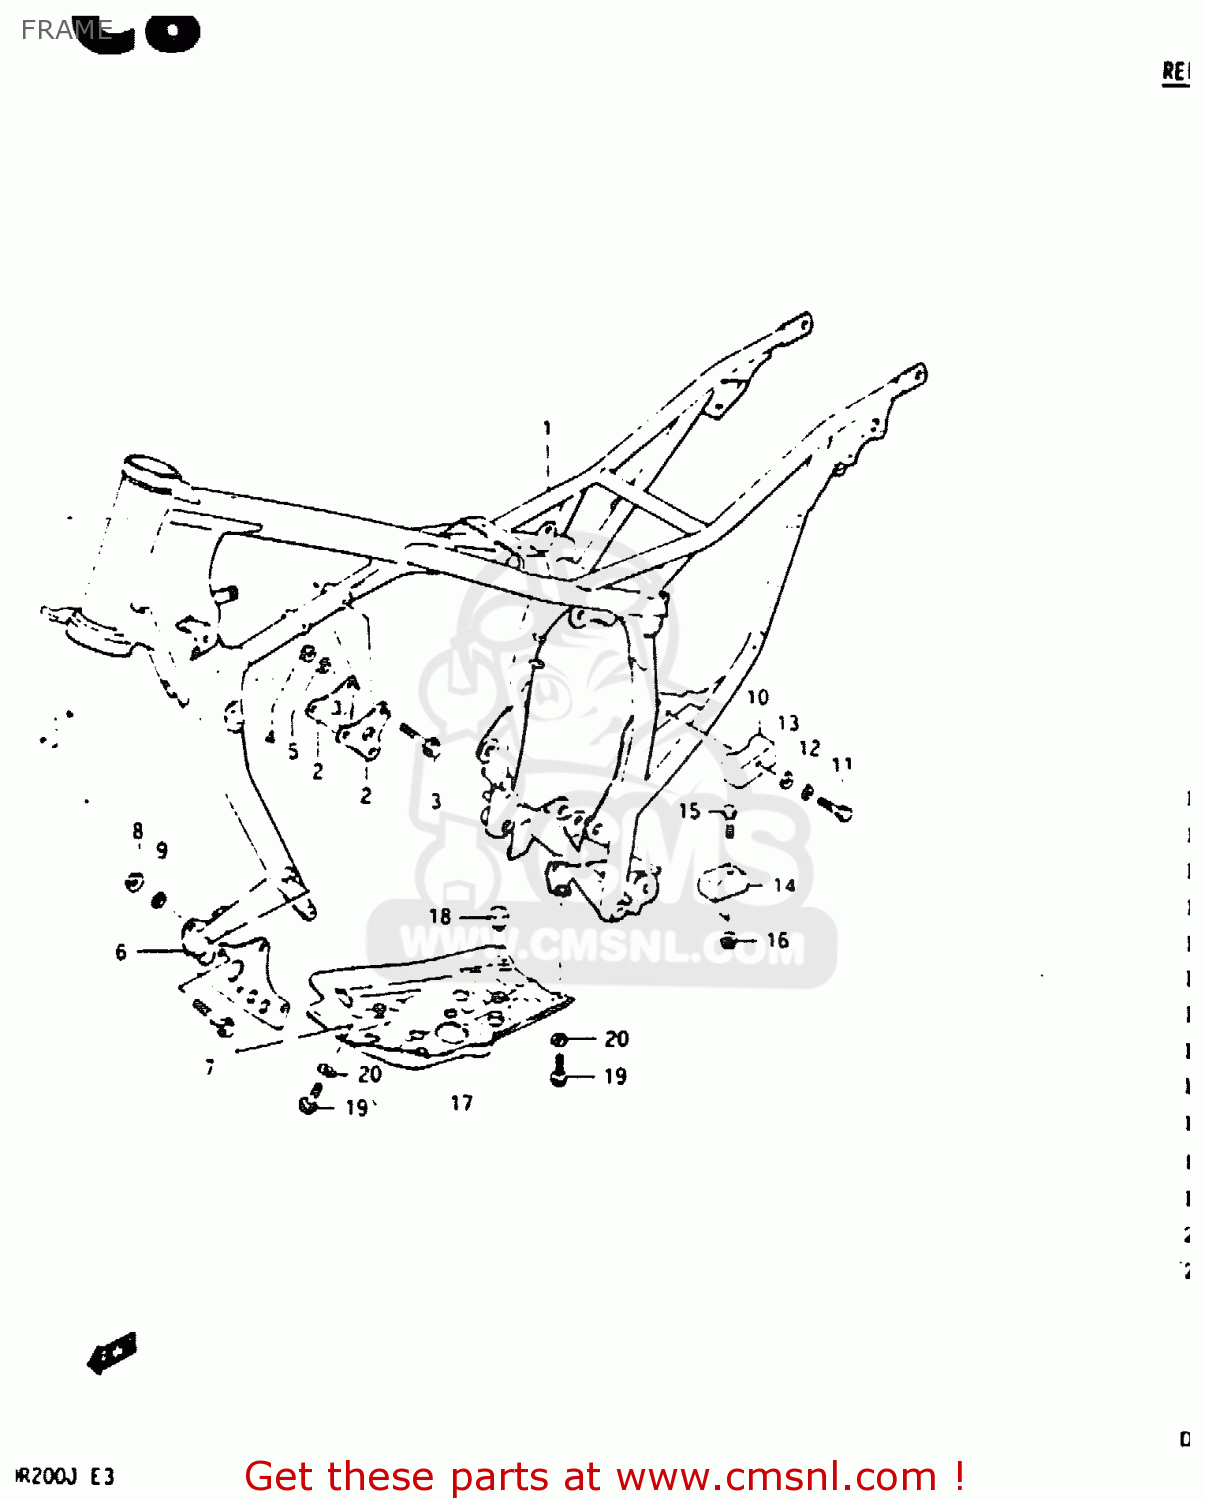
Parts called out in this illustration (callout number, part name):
1	FRAME
2	PLATE,ENGINE MOUNT UPR
3	BOLT
4	NUT
5	LOCK WASHER
6	PLATE,ENGINE MOUNTING
7	BOLT
8	NUT
9	LOCK WASHER
10	GUIDE,CHAIN
11	BOLT 6X35
12	WASHER,LOCK
13	WASHER
14	GUIDE,CH LENGTH CONTROL LWR
15	BOLT
16	NUT 6MM
17	PROTECTOR,ENGINE
18	CUSHION
19	BOLT
20	WASHER
